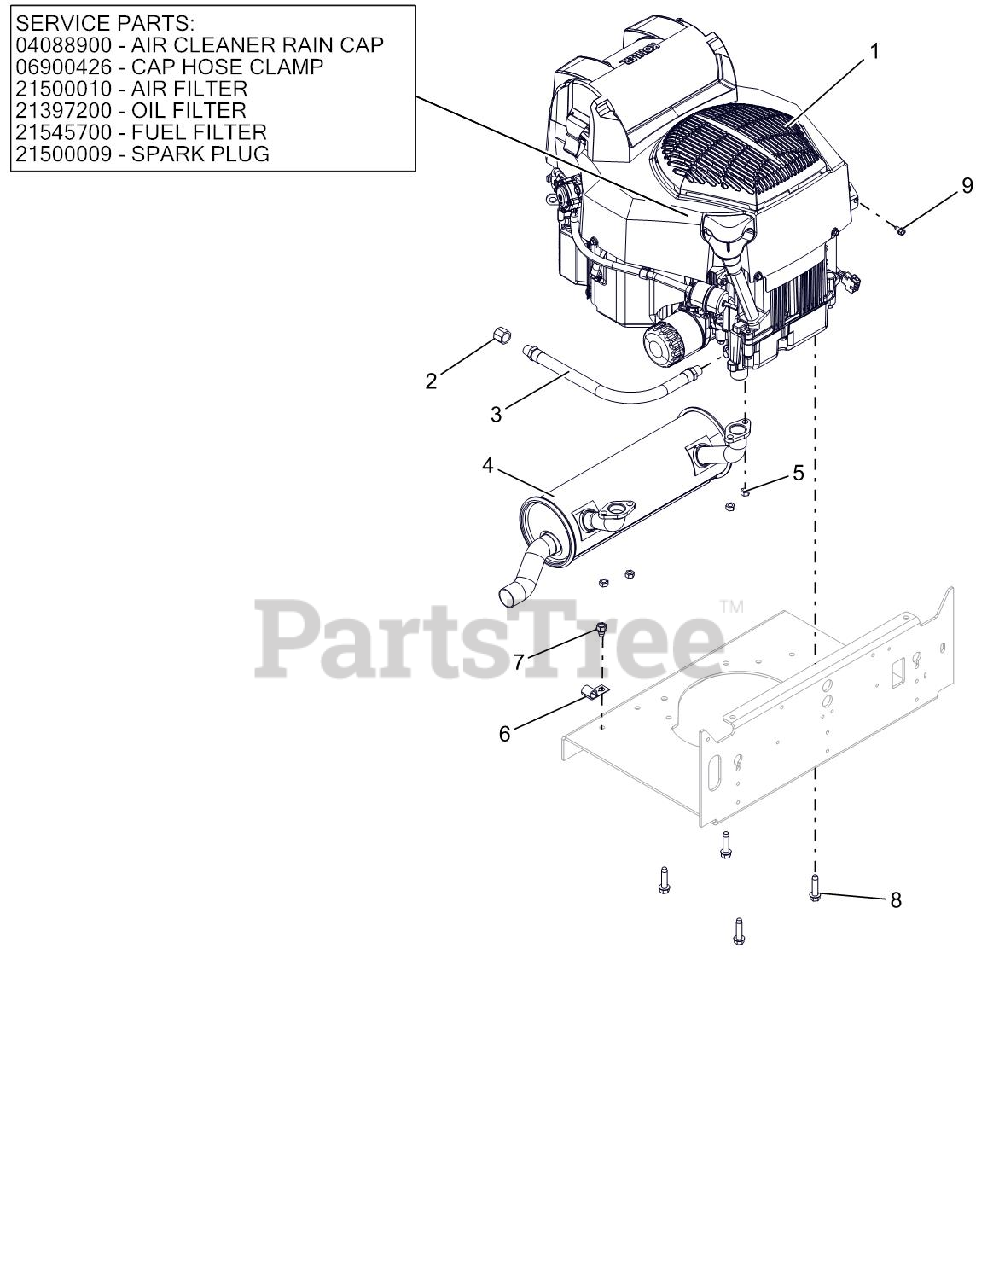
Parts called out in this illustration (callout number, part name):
1	FILTER, OIL - KOH CV20
1	CAP, KAW 11065-7025
1	CLAMP, HOSE #36 SS 1.813-2.75
1	AIR CLEANER, KOHLER CONFIDANT
1	FILTER-FUEL KOHLER COURAGE PRO
1	PLUG, SPARK KOHLER
1	ENGINE, KOHLER ZT740 CONFIDANT
2	PIPE CAP 3/8 NPT FEMALE
3	HOSE,HYD .38-14-0K M6N0-M6N0
4	MUFFLER, ZT730/ZT740
5	NUT-LK-TOP M8-1.25 YWZC
7	@SCR-TAP .38-16X.50 HWH TR YWZ
8	@SCR-TAP .38-16X1.50 HWH TR YZ
9	SCR-TAP .25-20X.50 HWH TR YWZ
